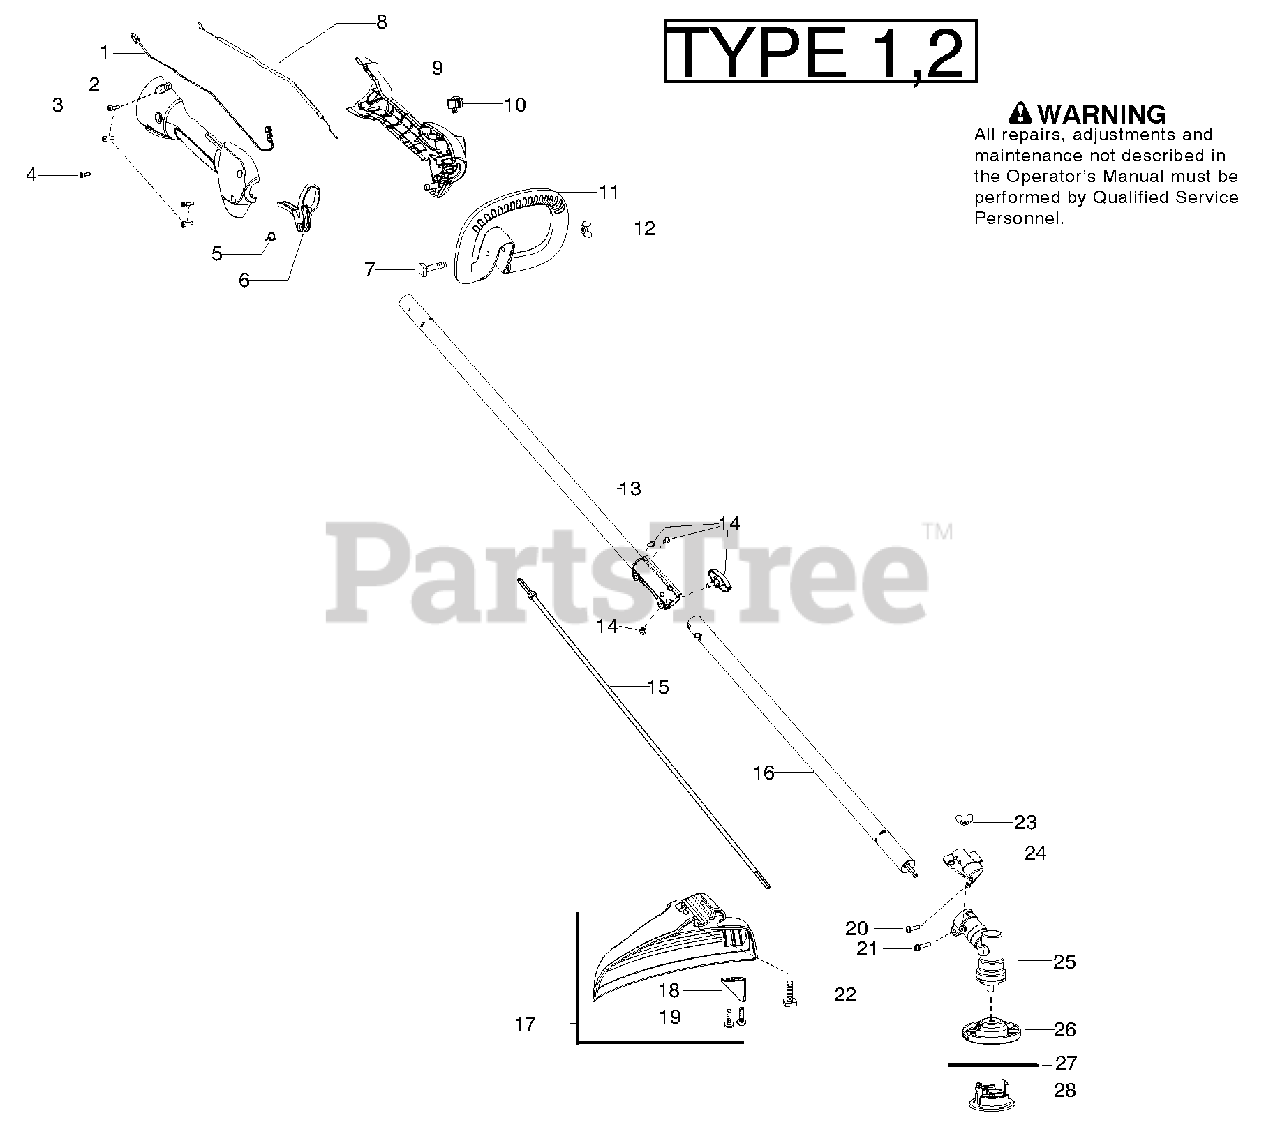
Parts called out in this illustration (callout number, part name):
1	Assy-Switch Wire
2	Housing-Throttle (RH)
3	Screw M4
4	Screw 10-14 x 1/2
5	Spring-Trigger
6	Kit - Trigger
7	Bolt - 1/4-20 x 2
8	Assy - Throttle Cable
9	Housing-Throttle (LH)
10	Kit-Switch
11	Assy - Handle Assist
12	Wingnut - 1/4-20
13	Kit - Driveshaft Upper
14	Kit - Knob / Screw
15	Flexshaft
16	Kit-Driveshaft Lower
17	Kit-Shield
18	Limiter-Line
19	Screw - 10-14 x 3/4
20	Screw - 8-16 x .593
21	Screw - 12-24 x .960
22	Bolt - 1/4-20 x 1-1/4
23	Wingnut - 1/4-20
24	Bracket - Shield
25	Assy - Gearbox 1"
26	Assy - Fixed Line Head
27	Accy - Line (12 pcs )
28	Cap - Fixed Line
